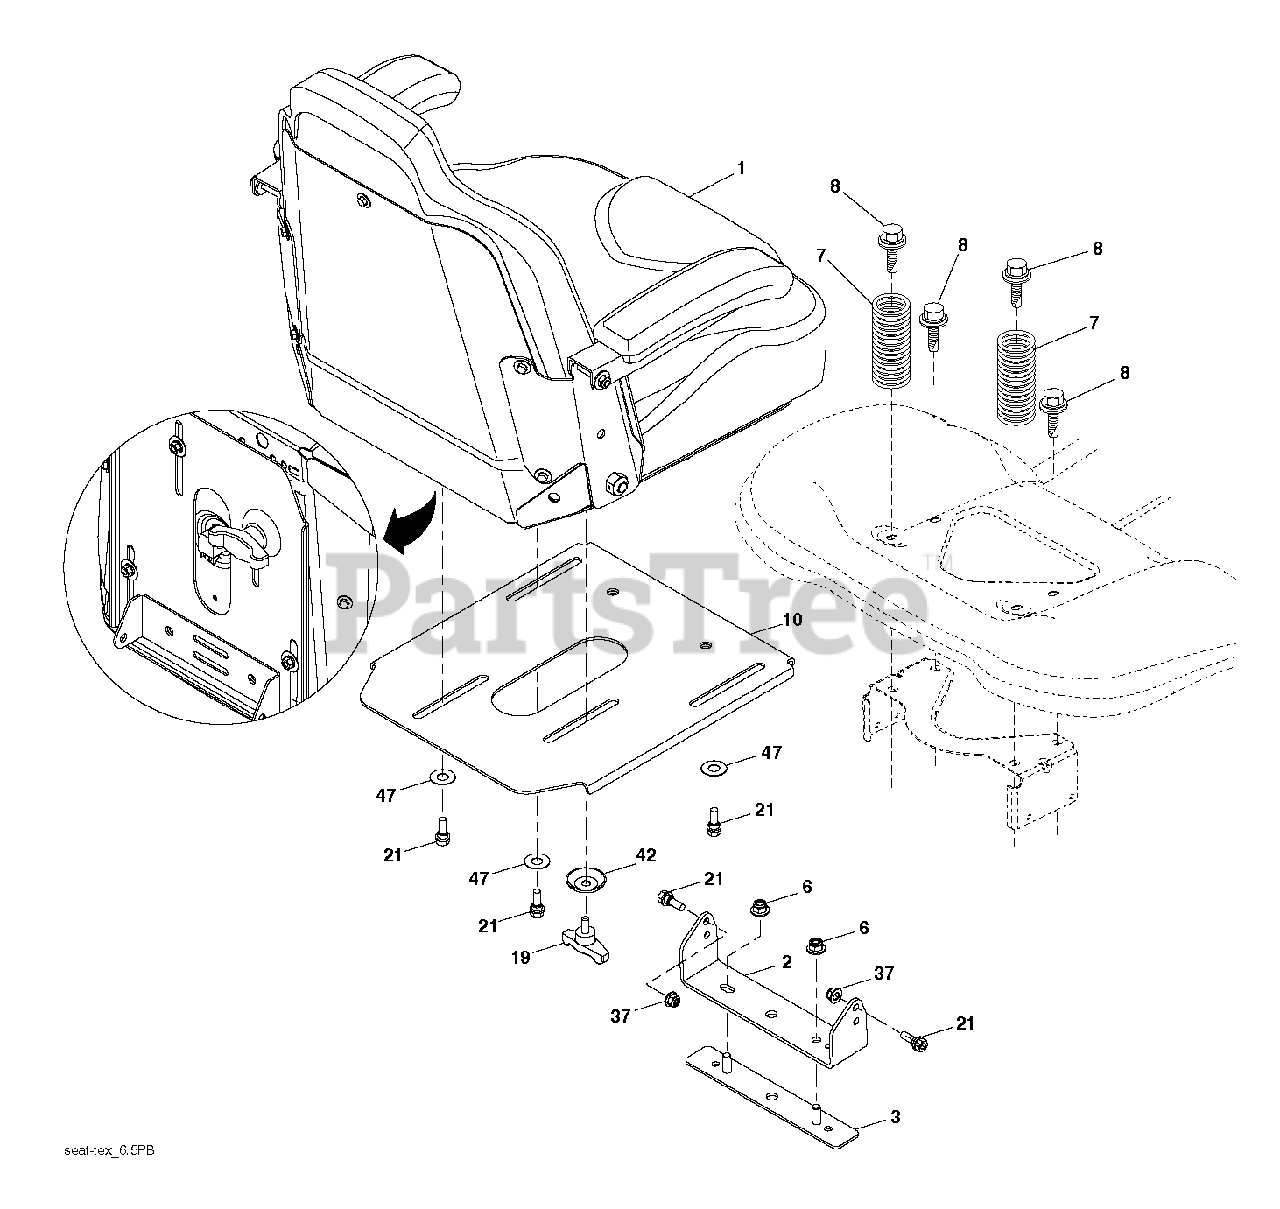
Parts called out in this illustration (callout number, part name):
1	SEAT TRACTOR MZ TRACTOR MZ 907
2	BRACKET PIVOT FENDER SEAT TRAC
3	BRACKET ASSEMBLY REINFORCEMENT
6	NUT 3/8-16 HEX FLG NYLOC ZD
7	SPRING COMPRESSION SEAT 300 SE
8	BOLT, 5/16-18 X 1 3/4
10	Bracket Assembly Plate
19	KNOB SEAT 5/16-18X3/4
21	BOLT SHOULDER 5/16-18 UNC
37	5/16-18 NYLOC FLANGE NUT
42	WASHER.CUP.SEAT.
47	WASHER NYLON .50 X 1.00 X .045
